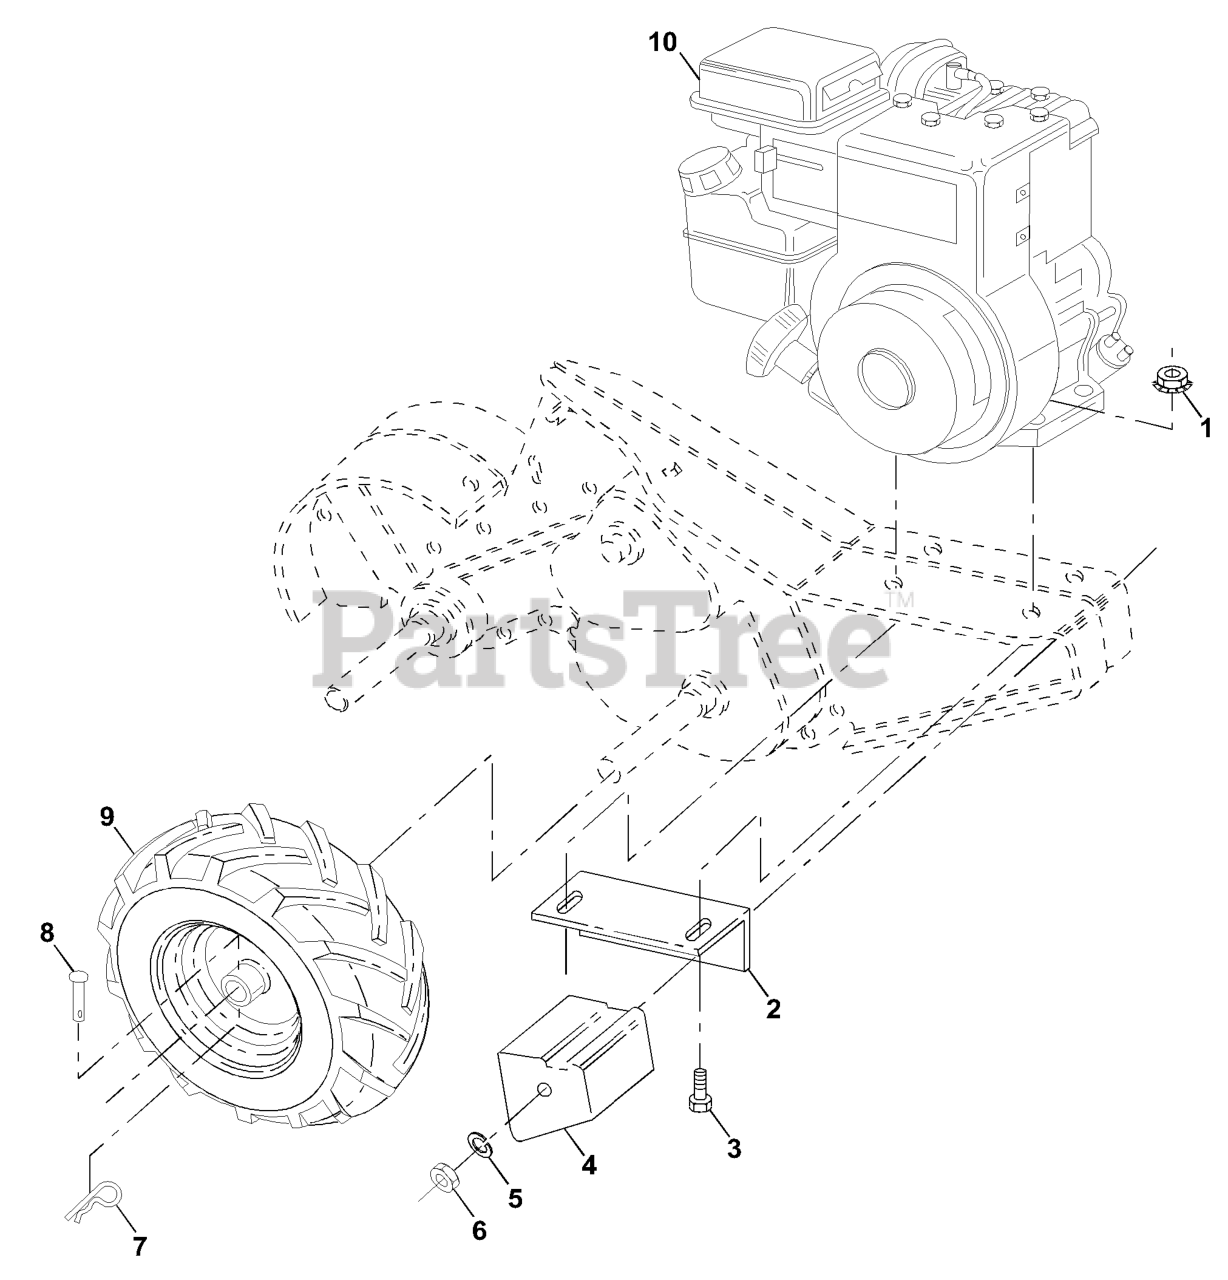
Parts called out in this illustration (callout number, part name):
1	NUT
2	DNO BRACKET RH CRT
3	BOLT
4	COUNTERWEIGHT, RH
5	WASHER, LOCK 3/8
6	NUT.HEX.3/8-16UNC
7	RETAINER M
8	RIVET,DRILLED
9	TIRE.13X5-6.CHEVRON.TILLER
9	RIM.ASM.6".SILVER
9	VALVE STEM LT
10	Engine, Briggs & Stratton
